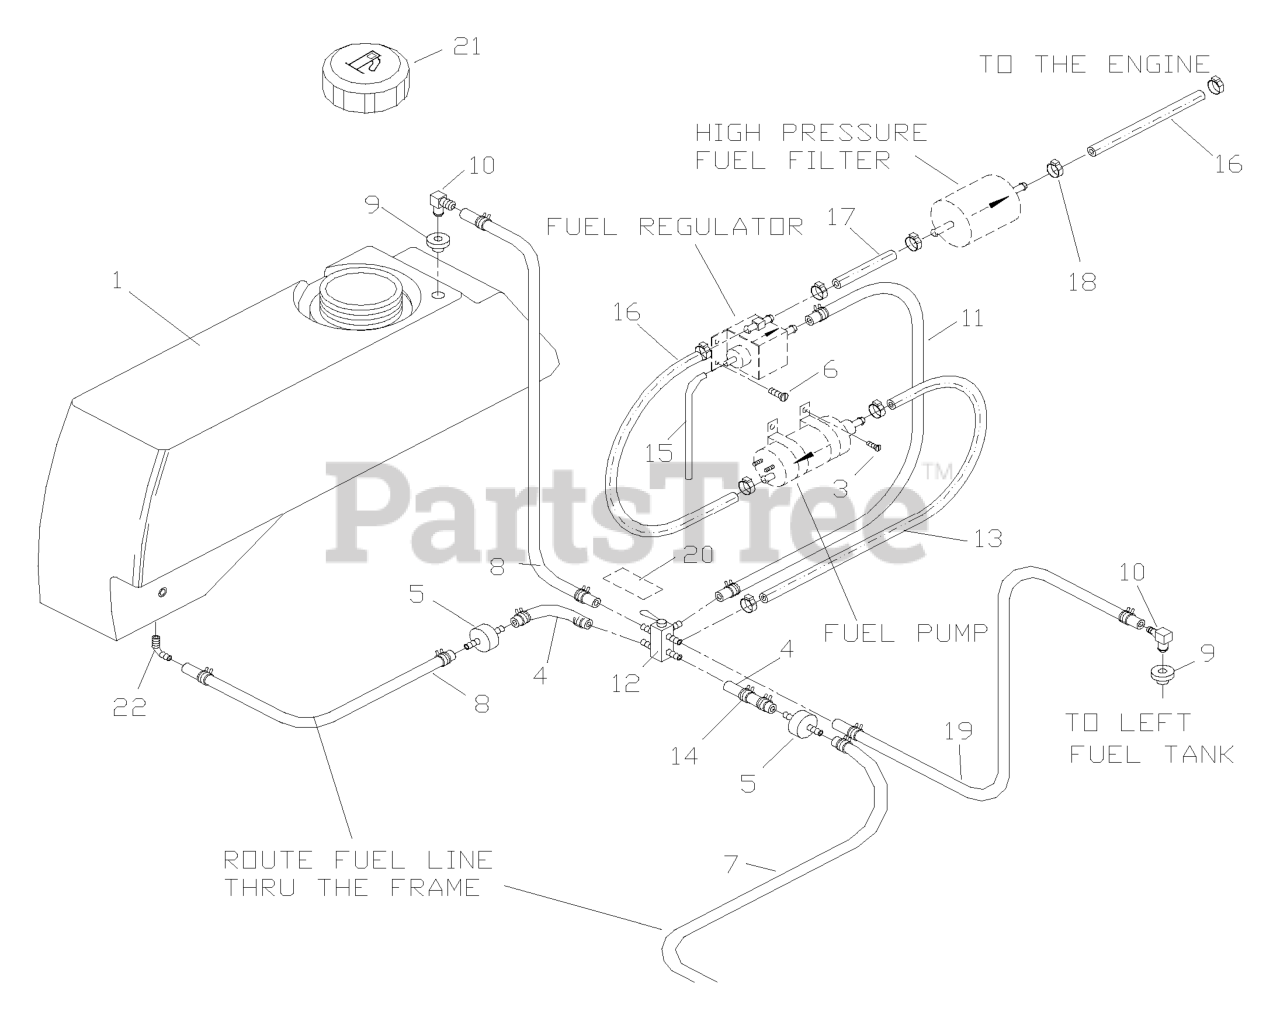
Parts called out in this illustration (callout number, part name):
1	FUEL TANK DIESEL RT
2	FUEL TANK DIESEL LT
3	SCREW #10 X 1/2 SELF TAPPING
4	GAS LINE 3 1/2"
5	FUEL FILTER
6	HEX CAP SCREW 1/4
7	FUEL LINE 29.5"
8	FUEL LINE 18"
9	RUBBER GROMMET
11	FUEL LINE 24"
12	FUEL VALVE
13	EFI HOSE - 18"
14	HOSE CLAMP
16	EFI HOSE - 8"
17	EFI HOSE - 4"
19	FUEL LINE 34"
20	FUEL VALVE DECAL
21	FUEL CAP ANTI-SPLASH
22	HOSE BARB 90 DEGREE
